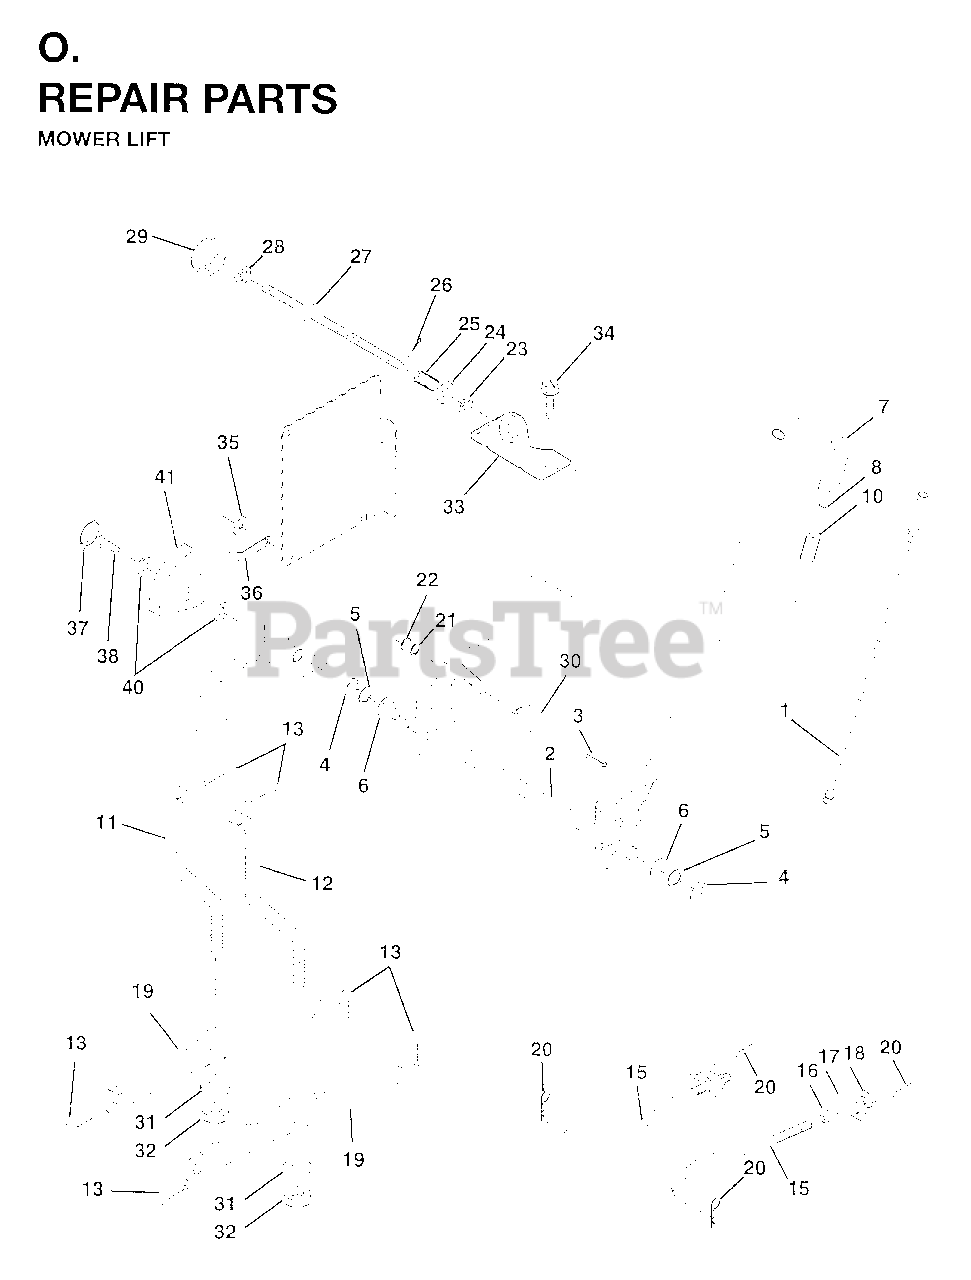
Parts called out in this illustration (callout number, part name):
1	WIRE, INNER HANDLE
2	SHAFT ARM LIFT RH
3	PIN GROOVE
4	RETAINING RING LT
6	BEARING.NYLON
7	GRIP HANDLE
8	PLUNGER BUTTON KIT
10	SPRING, COMP T
11	LINK LIFT LH
12	LINK LIFT RH
13	RETAINER SPRING
15	FRONT LINK
16	NUT 1/2 X 13
17	TRUNION
18	NUT
19	ARM.REAR.SUSPENSION
20	SPRING RETAINER
22	KLIP RING
25	SPRING**
26	COTTER PIN
27	ROD ADJ LIFT
28	NUT.HEX.3/8-16UNC
29	KNOB INF 3/8-16
30	TRUNION LT
31	BEARING PIVOT
32	NUT
36	HEIGHT INDICATOR PNTR
37	PLUG,HOLE
38	BOLT
41	HEIGHT INDICATOR
